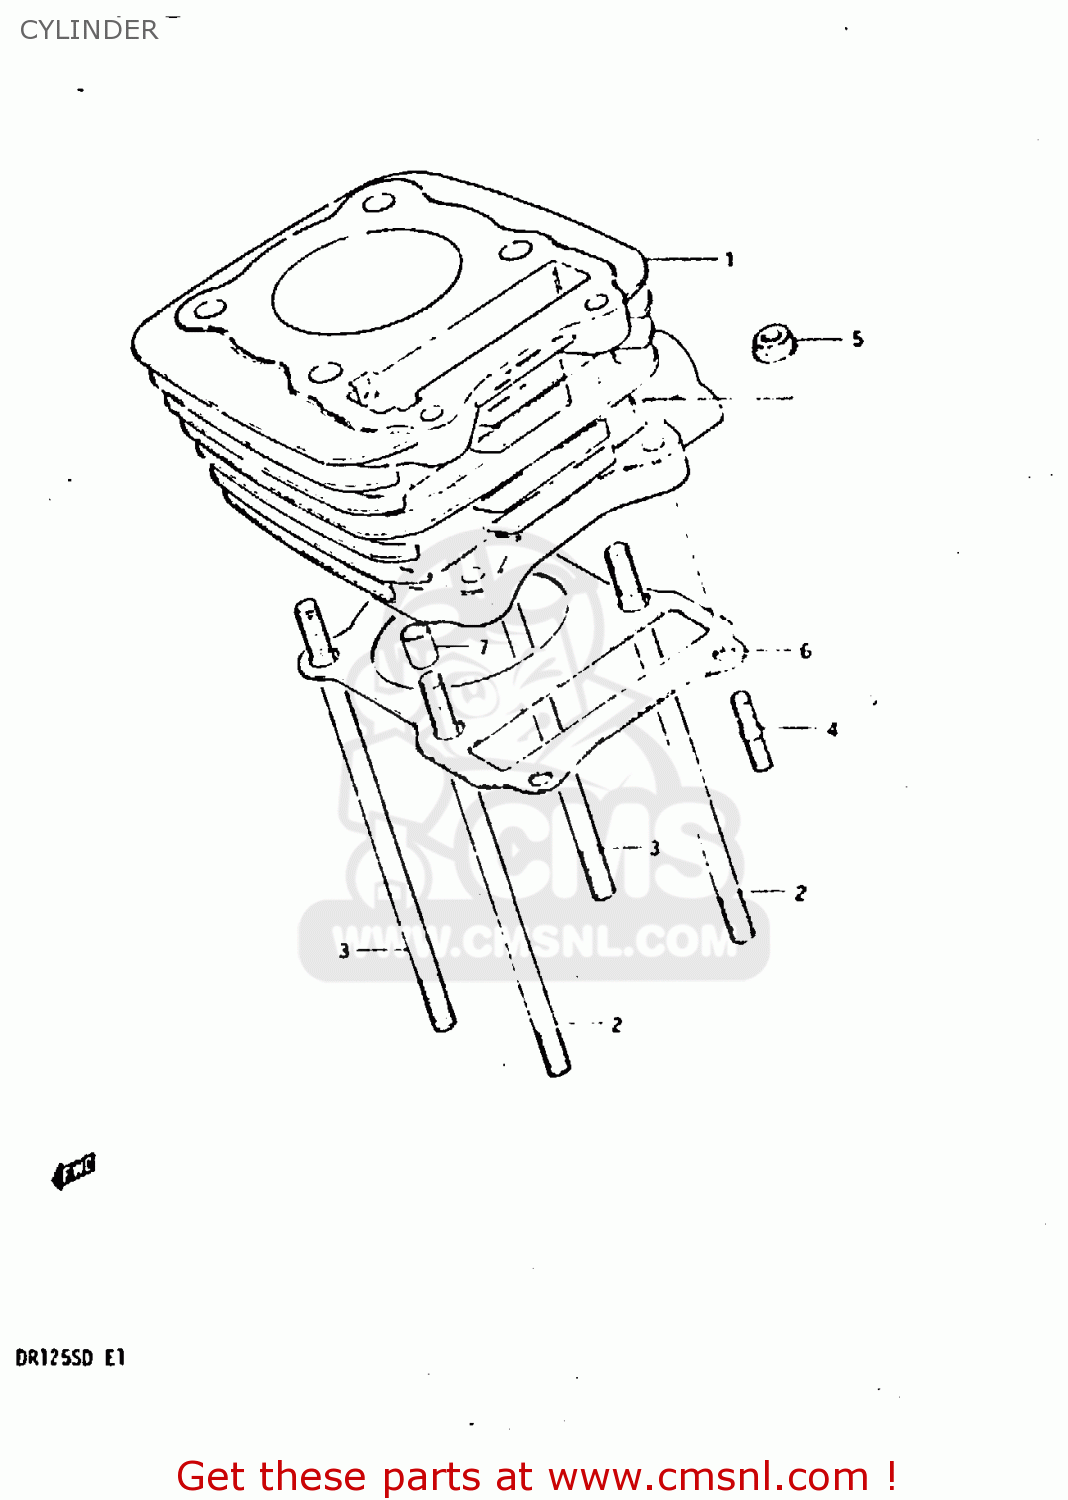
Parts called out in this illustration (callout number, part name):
1	CYLINDER
2	BOLT,STUD
3	BOLT,STUD
4	STUD 6X25
5	NUT
6	GASKET,CYLINDER (MCA)
7	PIN
